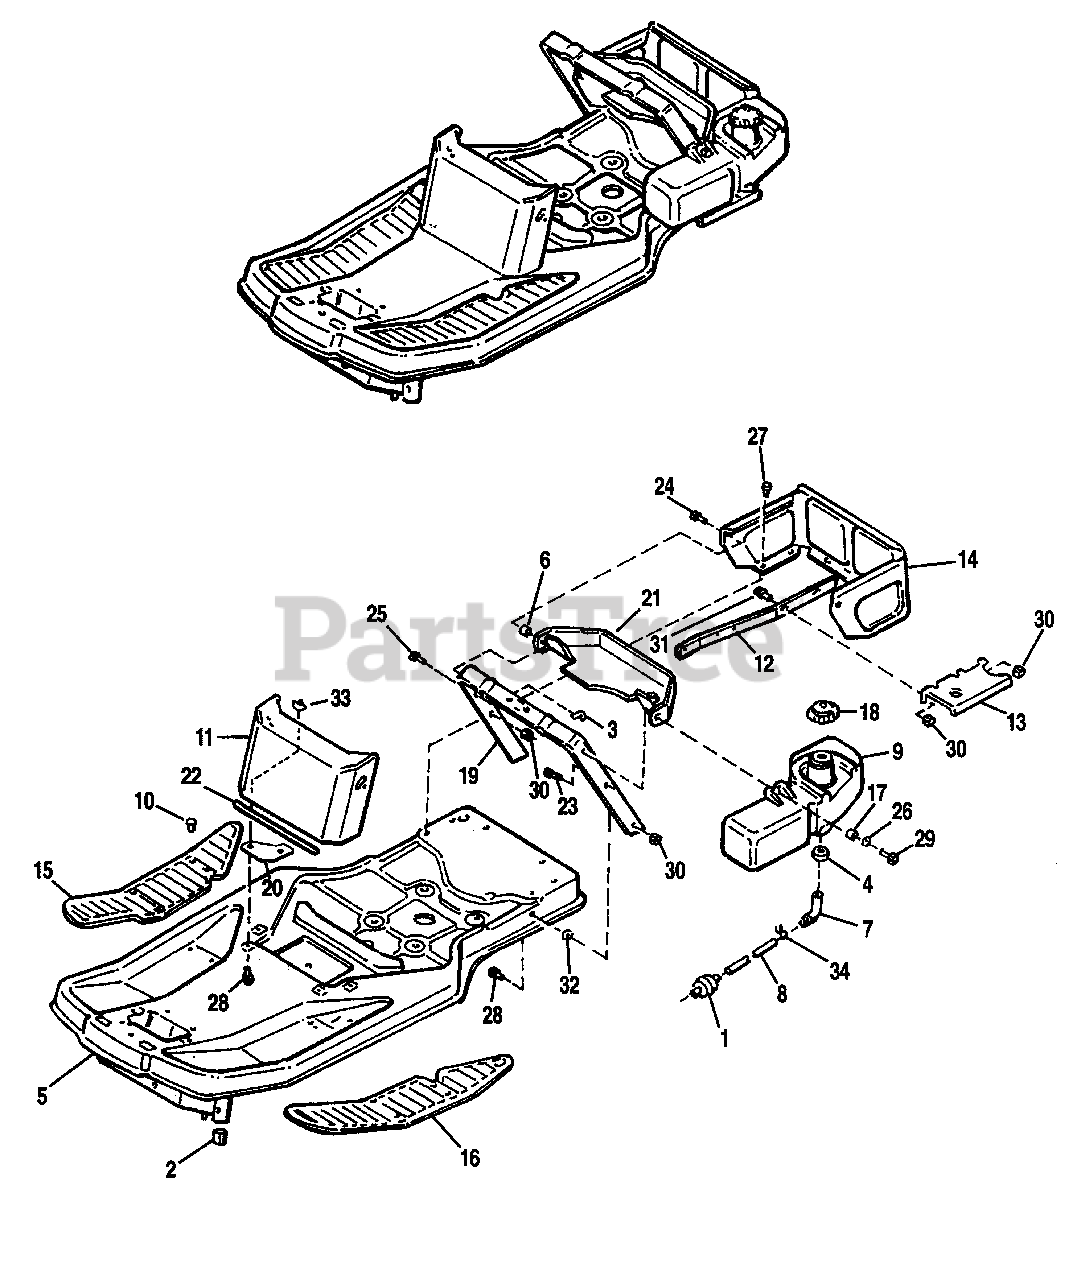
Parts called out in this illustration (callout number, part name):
1	FUEL FILTER
3	CLIP
4	BUSHING, Rubber
5	FRAME ASSY. (Incl. Ref. No. 2)
8	HOSE, Fuel Tank
9	FUEL TANK (Incl. Ref. No. 1, 4, 7 & 34)
11	PANEL, Front
12	STRAP, Fuel Tank, Brace
13	SUPPORT, Fuel Tank
14	SHROUD, Rear
15	PAD, Foot Rest, RH
16	PAD, Foot Rest, LH
17	SPACER, 21/64 x 1/2 x 21/64
18	CAP, Fuel Tank, Vented
19	U-SUPPORT, Seat Deck
20	PLATE, Front Panel
21	DUCT, Air Inlet
22	SEAL, Front Plate
23	CAPSCREW, Hex Hd., 5/16-18 x 1-1/4
24	CAPSCREW, Hex Hd., 5/16-18 x 1-3/4
25	CAPSCREW, Hex Hd., 1/4-20 x 3/4
26	WASHER, Plain, 13/32 x 7/8 x 5/64
27	SCREW, Hex Hd., Taptite, 1/4-20 x 1/2
28	CAPSCREW, Hex Hd., Whizlock, 5/16-18 x 3/4
29	SCREW, Hex, Taptite, 5/16-18 x 1-1/4
30	NUT, Hex, Flange, Whizlock, 5/16-18
31	CARRIAGE BOLT, 5/16-18 x 3/4
32	PAL NUT, 5/16
33	PAL NUT, 5/16-18
34	CLAMP, Hose
